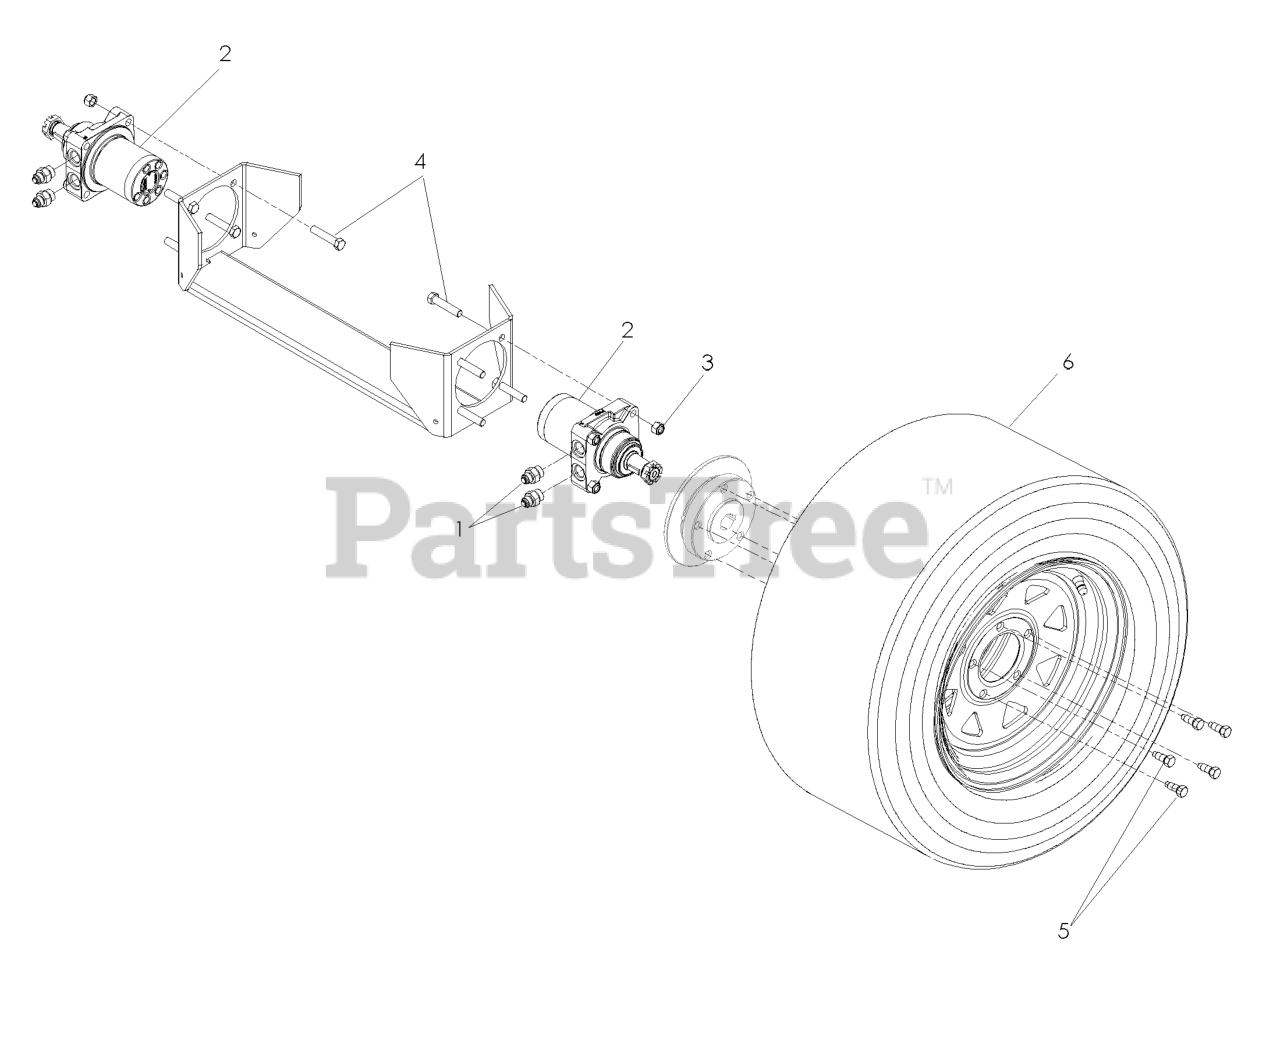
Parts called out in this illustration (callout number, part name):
1	CONNECTOR, STRAIGHT
2	WHEEL MOTOR, TJ
3	NUT 1/2-13 HEX NYLOC ZD
4	HEX SCREW 1/2-13 X 2.5" GR 5
5	HUB BOLT
6	WHEEL.R.TS.23X10.5-12.C.MS
